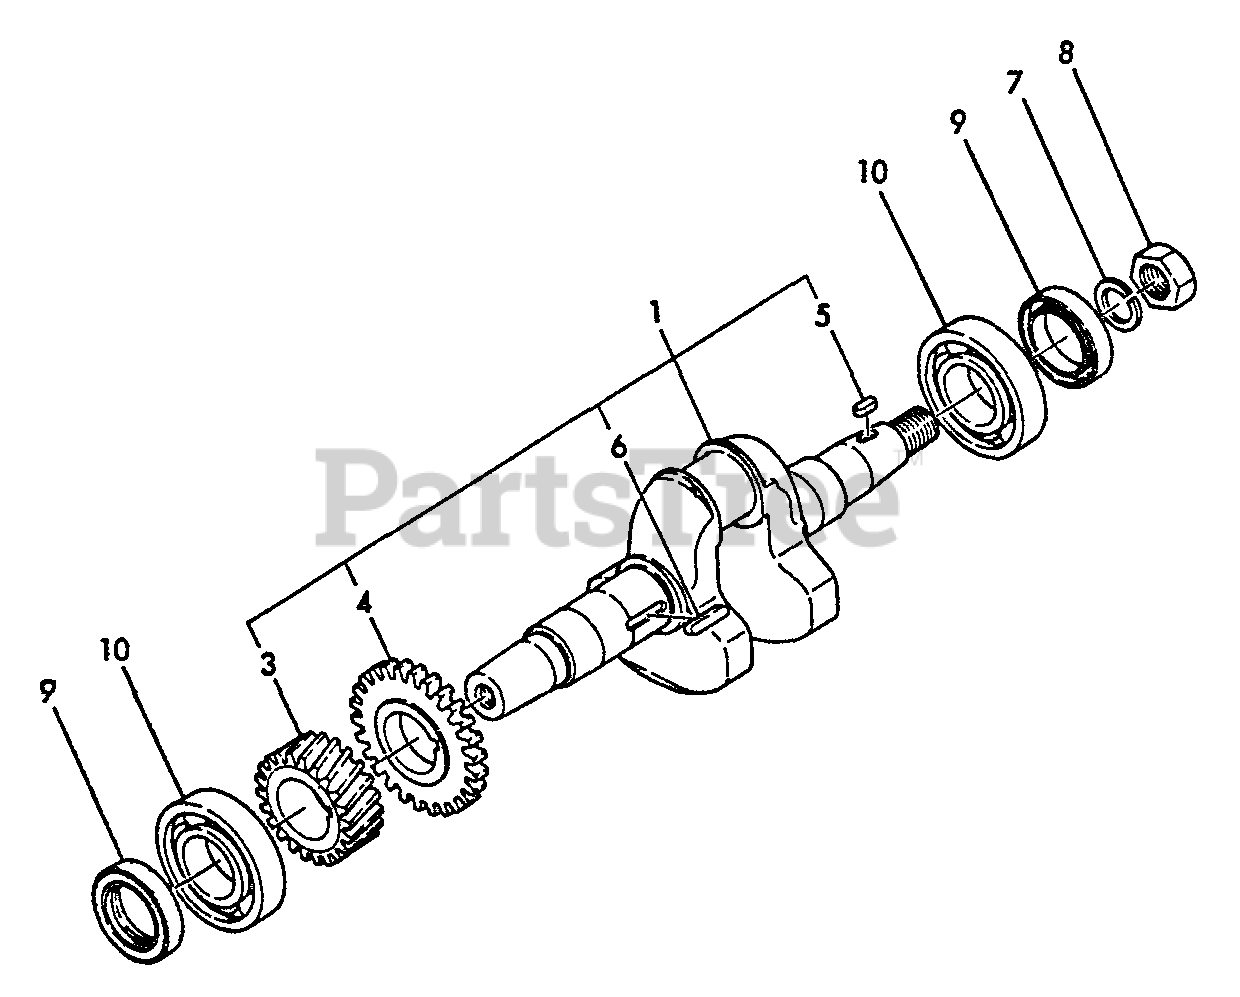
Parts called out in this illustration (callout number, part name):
1	CRANKSHAFT ASSY
3	GEAR, CRANKSHAFT
4	GEAR, BALANCER
5	KEY - 4X10
6	KEY - 4X24
7	LOCKWASHER - 10
8	NUT - 16
9	SEAL, OIL
10	BEARING, BALL - 6206C4
